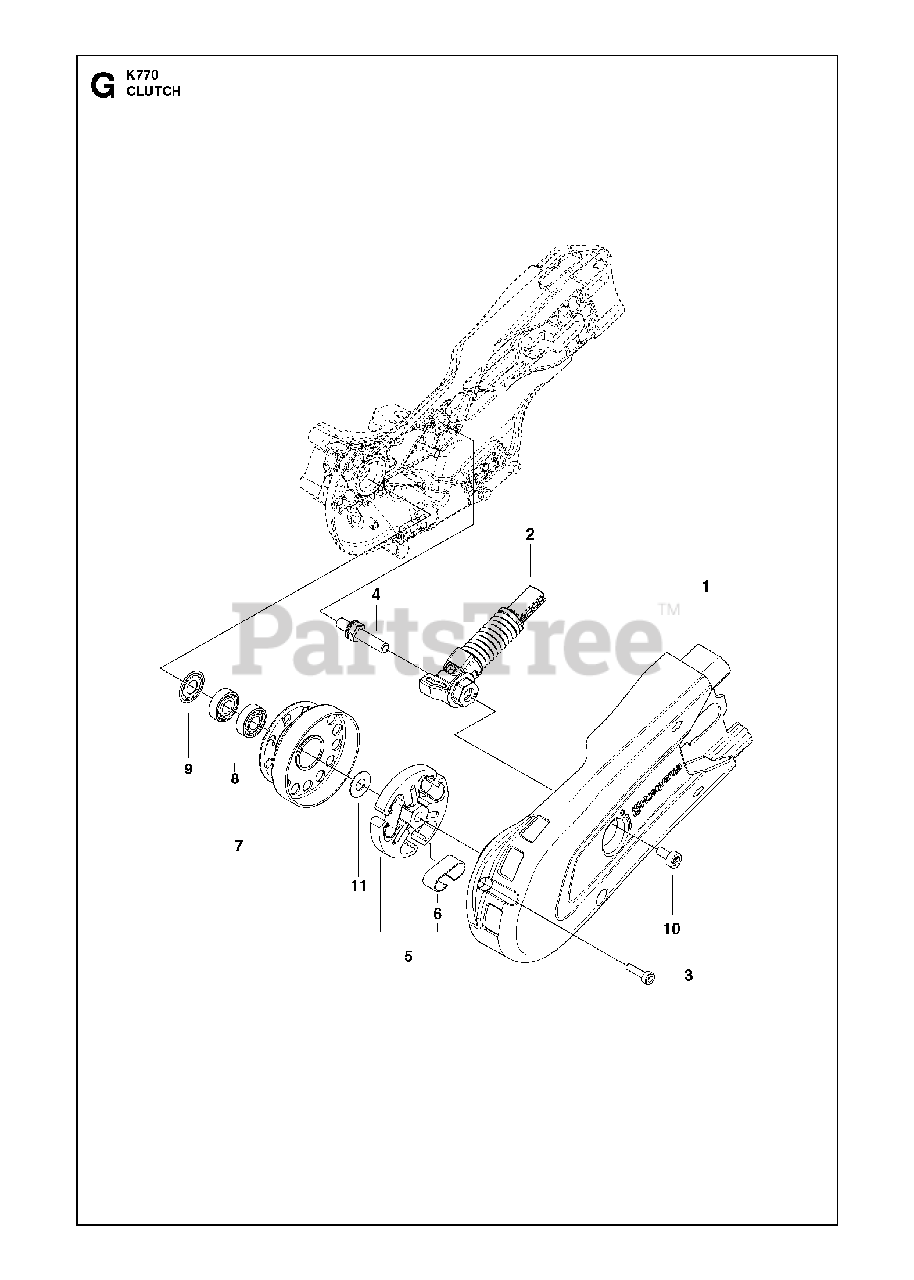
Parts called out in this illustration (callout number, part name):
3	SCREW ITXSCM
6	CLUTCH SPRING
8	BALL BEARING
10	SCREW ITXSCM
11	WASHER
